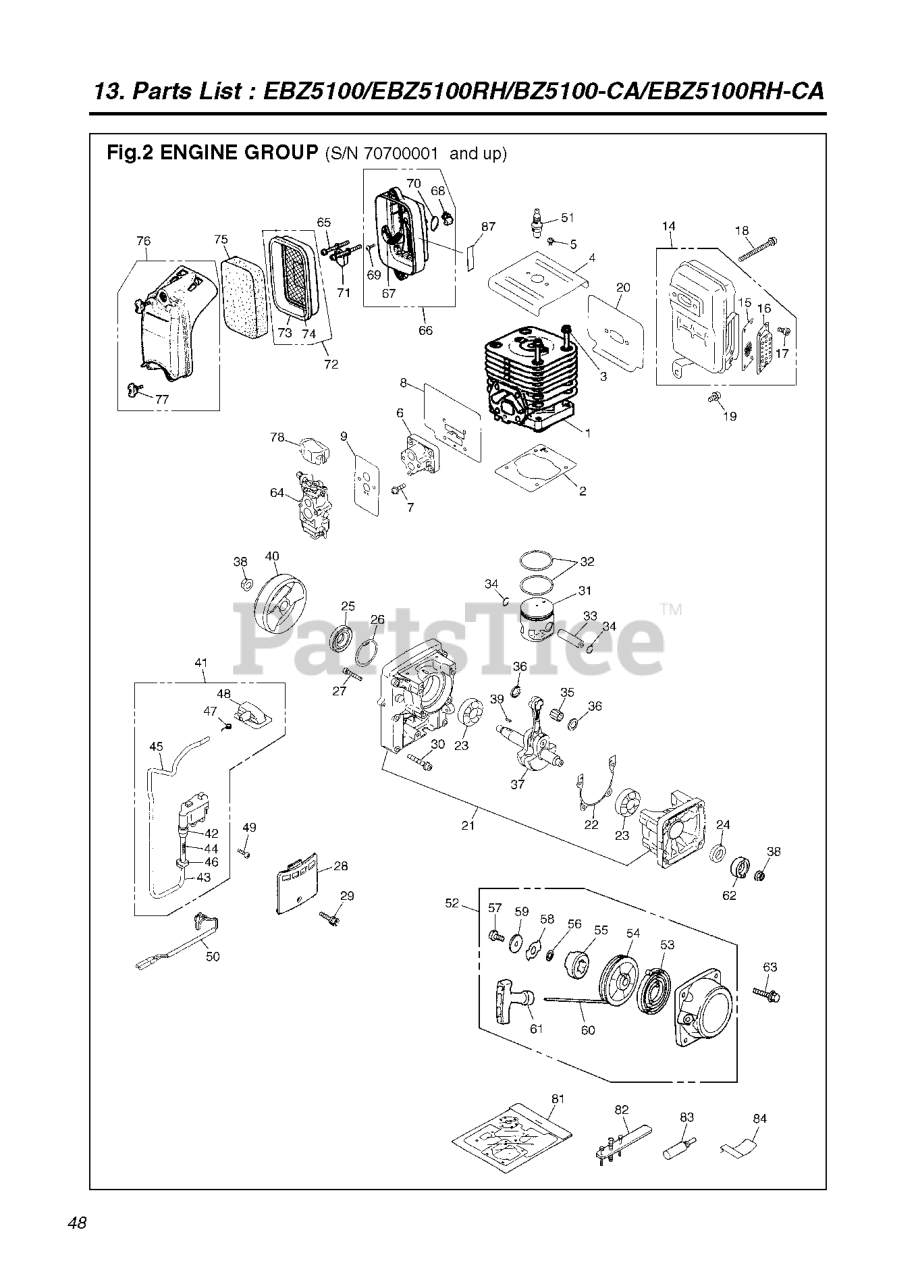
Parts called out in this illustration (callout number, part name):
1	CYLINDER
3	BOLT
4	CYLINDER COVER
6	INSULATION
8	GASKET,INSULATOR
14	MUFFLER ASSY
15	SPARK ARRESTOR SCREEN
16	EXHAUST DUCT
20	GASKET
21	CRANKCASE
26	SNAP RING
30	BOLT
32	PISTON RING
33	PISTON PIN
34	SNAP RING
37	CRANKSHAFT
39	KEY
41	%COIL ASSY
42	CAP
45	RP TUBE-A
46	GROMMET
50	CORD-COMP
51	PLUG CMR7H
52	STARTER ASSY
54	STARTER PULLEY
55	STARTER PAWL
58	RETAINER
59	WASHER
60	CHORD
62	PULLEY
64	CARBURETOR
66	CARBURETOR BODY
67	PLATE
69	SCREW
72	GASKET
74	SCREEN
75	AIR FILTER
76	COVER ASSY.
81	GASKET KIT
82	PULLER ASSY
87	LABEL,CHOKE
